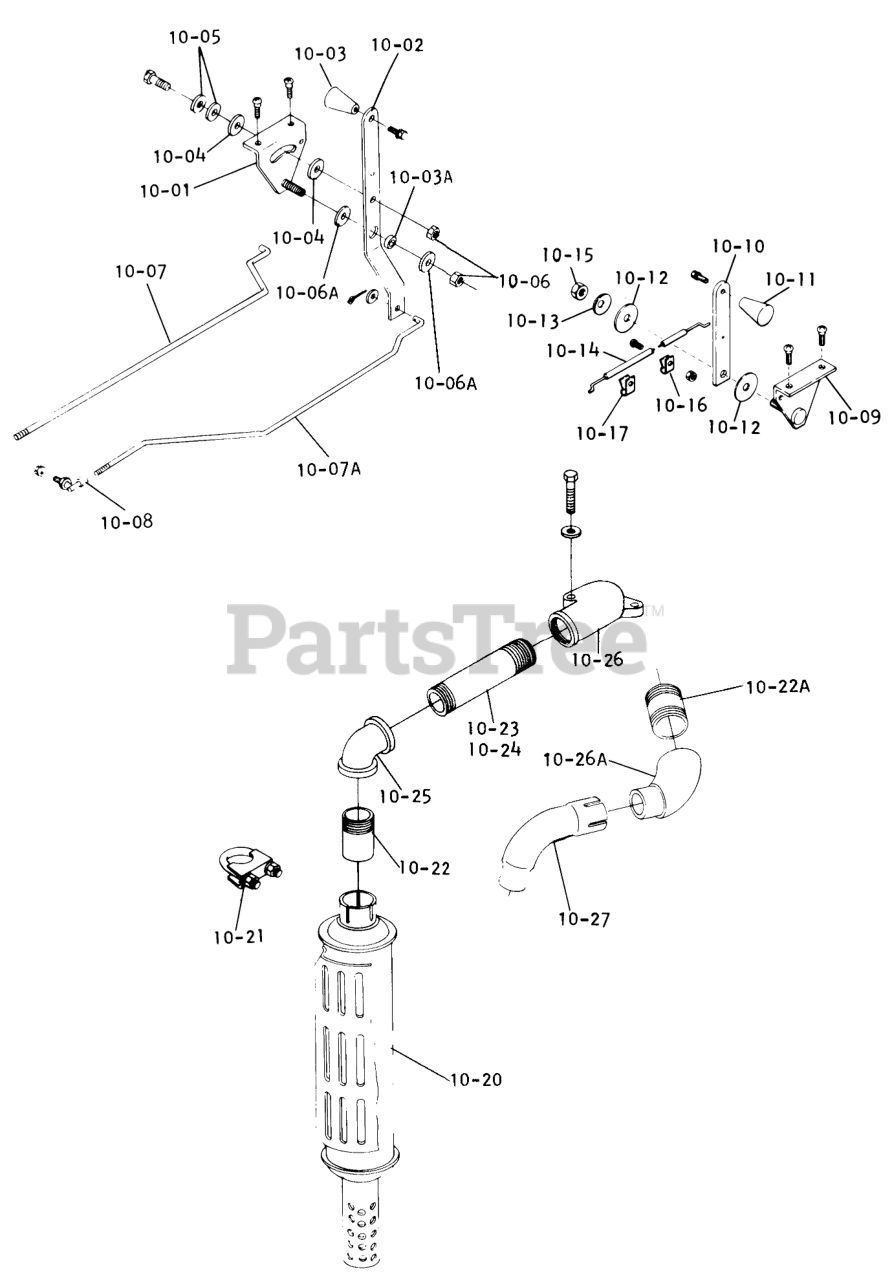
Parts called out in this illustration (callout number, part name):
10-01	Assy-Bracket
10-02	Handle Throttle
10-03	Knob
10-03A	SPACER CLUTCH ARM
10-04	FRICTION WASHER
10-05	WASHER-SPRING DISC
10-06	NUT
10-06A	Washer-3/8
10-07	Rod-Throttle
10-07A	Rod-Throttle
10-08	BALL JOINT ASSY R
10-09	Assy-Bracket
10-10	HANDLE
10-10	Assy-Bracket
10-12	FRICTION WASHER
10-13	WASHER-SPRING DISC
10-14	CABLE CHOKE CONTROL
10-14	CABLE-CHOKE CONTROL
10-16	CLIP BOWDEN WIRE
10-17	THROTTLE CONTROL CLP
10-20	Bracket
10-20	ASSY-MUFFLER
10-21	ASSY-MUFFLER CLAMP
10-22	Nipple
10-22A	NIPPLE-EXHAUST 1X4
10-23	Nipple 2 1/2 in. Long
10-24	Nipple 5 in. Long
10-25	ELBOW
10-26	Fitting Exhaust RH
10-27	TUBE-INLET
10-30	Fuel Tank
10-30A	Flanged Nut
10-31	Edge Trim
10-32	GAUGE CAP
10-33	FILTER & VALVE ASSY
10-34	Fuel Line 62
10-35	Pump Fuel
10-36	Coupling
10-37	FITTING STRAIGHT
10-38	CLAMP-HOSE
10-40	Hose
10-41	Filter
10-43	Bracket
10-44	Spacer
